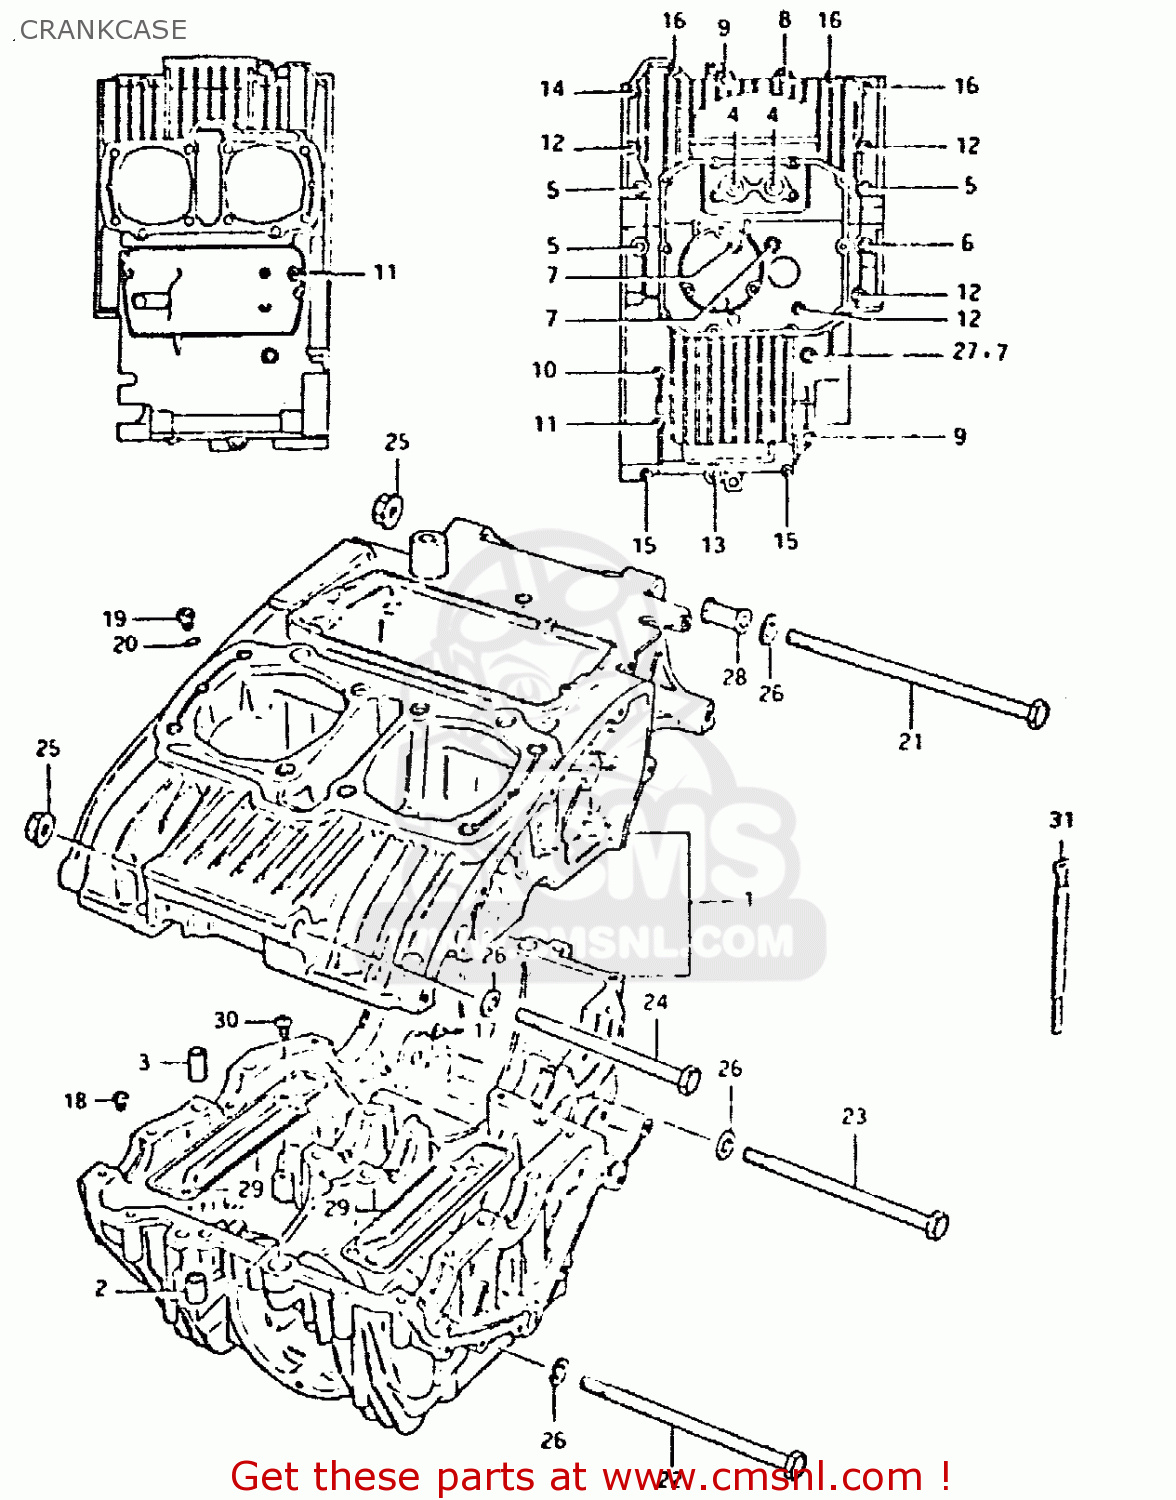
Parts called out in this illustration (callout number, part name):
1	CRANKCASE ASSEMBLY
2	PIN(10.4X13X22)
3	PIN (11X20)(SUS)
4	BOLT
5	BOLT
6	BOLT
7	BOLT
8	BOLT 8X65
9	BOLT (8X45)
10	BOLT
11	BOLT
12	BOLT (6X90)
13	BOLT (6X70)
14	BOLT 6X65
15	BOLT ,6X50
16	BOLT,UNDER
17	JET
18	JET
19	JET
20	O RING(D:1.05,ID:3.1)
21	BOLT 10X250
22	BOLT(10X210)
23	BOLT 10X160
24	BOLT
25	NUT 10MM
26	WASHER
27	GASKET 8.2X14X1 (NAS)
28	SPACER,ENGINE MOUNT
29	PLATE,OIL SEPARATOR
30	SCREW
31	CLAMP
